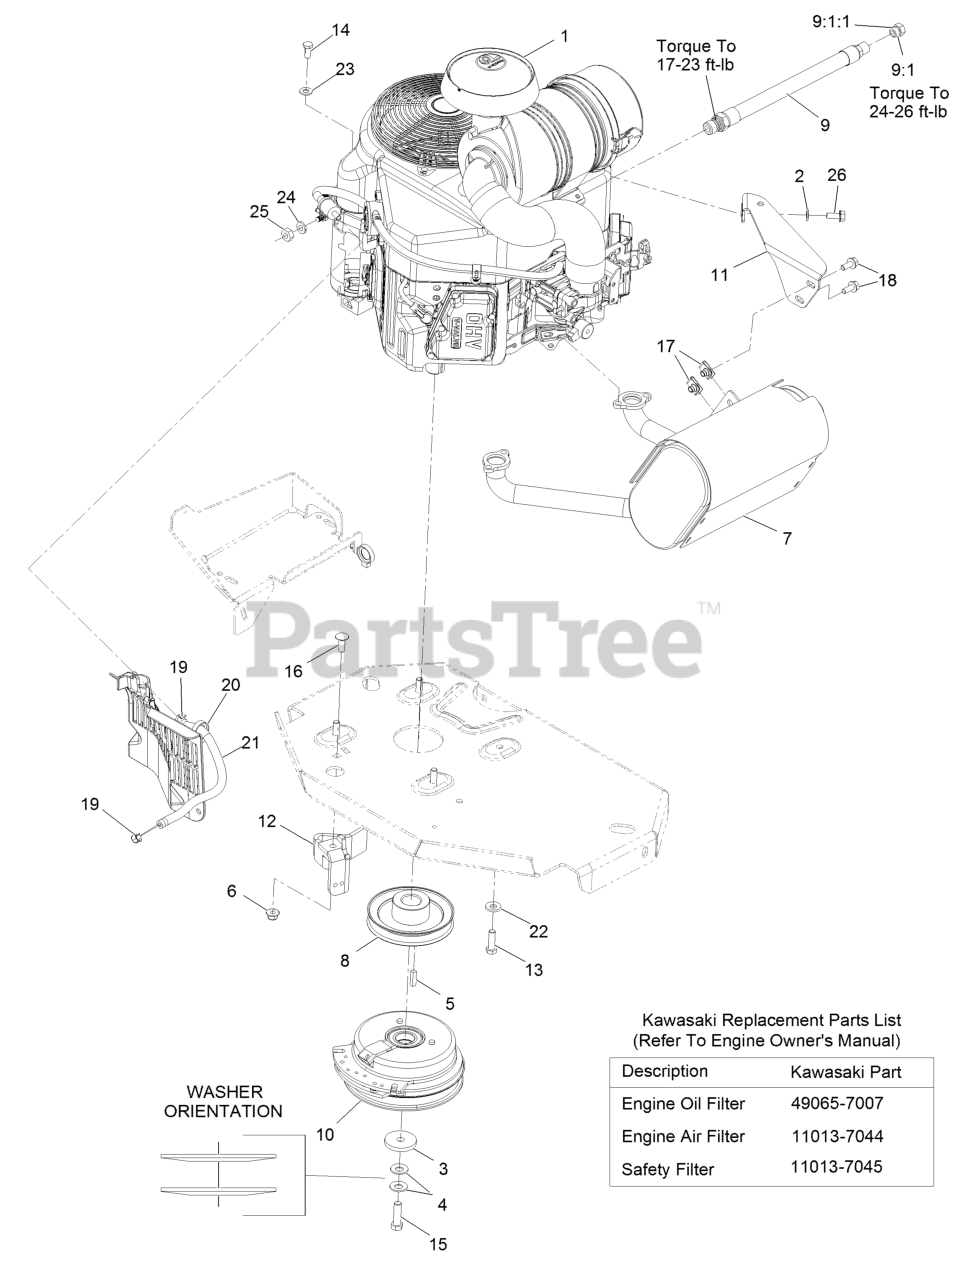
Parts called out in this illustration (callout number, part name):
2	WASHER-SPRING
3	WASHER-CLUTCH
4	WASHER-SPRING
6	NUT-HF, NI
7	MUFFLER
8	SHEAVE-PUMP, DRIVE
9	ENGINE OIL DRAIN HOSE ASM
9:1	PLUG-HH
9:1:1	O-RING
11	BRACKET-MUFFLER
12	CLUTCH-ANCHOR
13	SCREW-HH
14	SCREW-HH
15	SCREW-HH 7/16-20 X 1 1/2 W/LOCTITE
16	SCREW-CARR
18	SCREW-HHF
19	CLAMP-HOSE
20	CLAMP-HOSE
21	HOSE-FUEL
22	WASHER-BELLEVILLE
23	WASHER-PLAIN
24	WASHER-FLAT
25	NUT-HEX
26	SCREW-HHF
